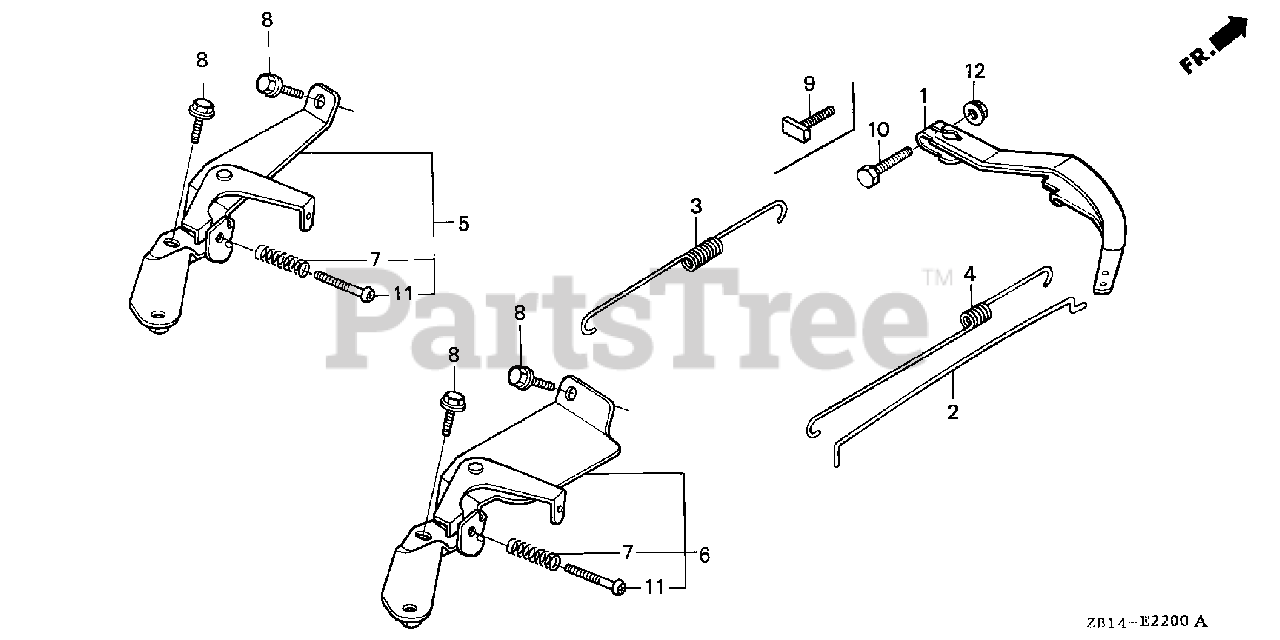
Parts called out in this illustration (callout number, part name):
1	ARM, GOVERNOR
2	ROD, GOVERNOR
3	SPRING, GOVERNOR
4	SPRING, THROTTLE RETURN
6	CONTROL ASSY.
7	SPRING, CONTROL ADJUSTING
8	BOLT, FLANGE (6X12) (CT200)
9	BOLT, GOVERNOR ARM
10	BOLT, HEX. (6X20)
11	SCREW, PAN (5X35)
12	NUT, FLANGE (6MM)
